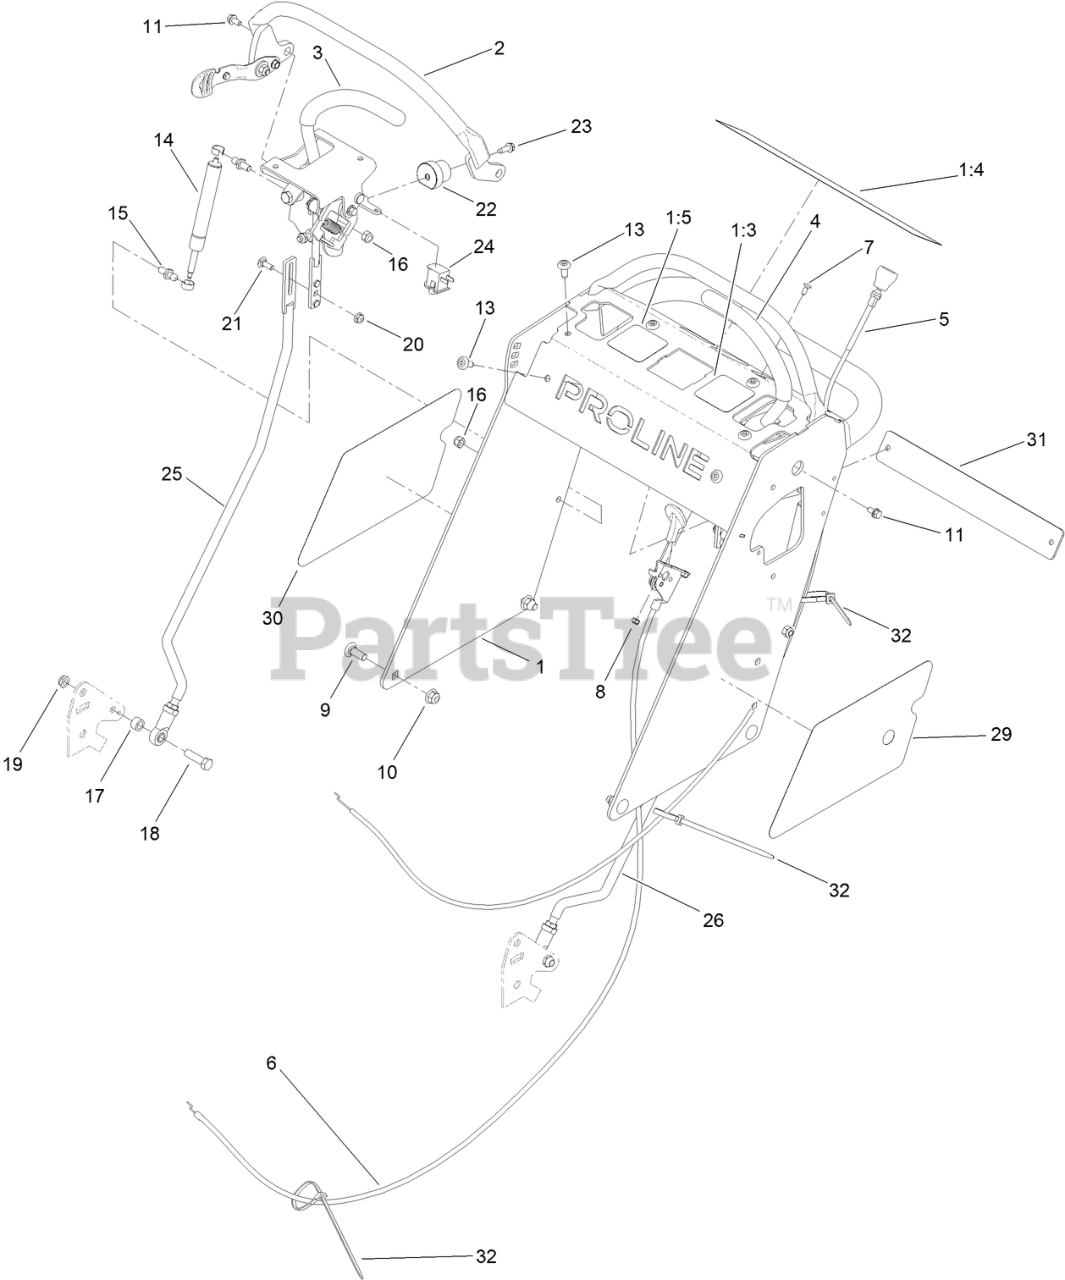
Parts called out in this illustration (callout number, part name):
1	TOWER ASM
1:3	DECAL-OPC CONTROL, LEFT
1:4	DECAL-WARNING, CONTROL
1:5	DECAL-OPC CONTROL, RIGHT
2	REFERENCE BAR ASSEMBLY
3	CONTROL HANDLE ASM, RH
4	CONTROL HANDLE ASM, LH
5	CABLE, CHOKE
6	CONTROL-THROTTLE
7	SCREW-CARR
8	NUT-LOCK, NI
9	SCREW-CARR
10	NUT-HF, NI
11	SCREW-HWH
14	DAMPER
15	STUD-BALL
16	NUT-LOCK, NI
17	SPACER
18	SCREW-HH
20	NUT-HF
21	BOLT-CARR
23	SCREW-HWHTF
24	SWITCH-BAIL
25	CONTROL ROD ASM, RH
26	CONTROL ROD ASM, LH
29	DECAL-PROLINE HDX, LH
30	DECAL-PROLINE HDX, RH
31	PLATE-COVER
32	TIE-CABLE
